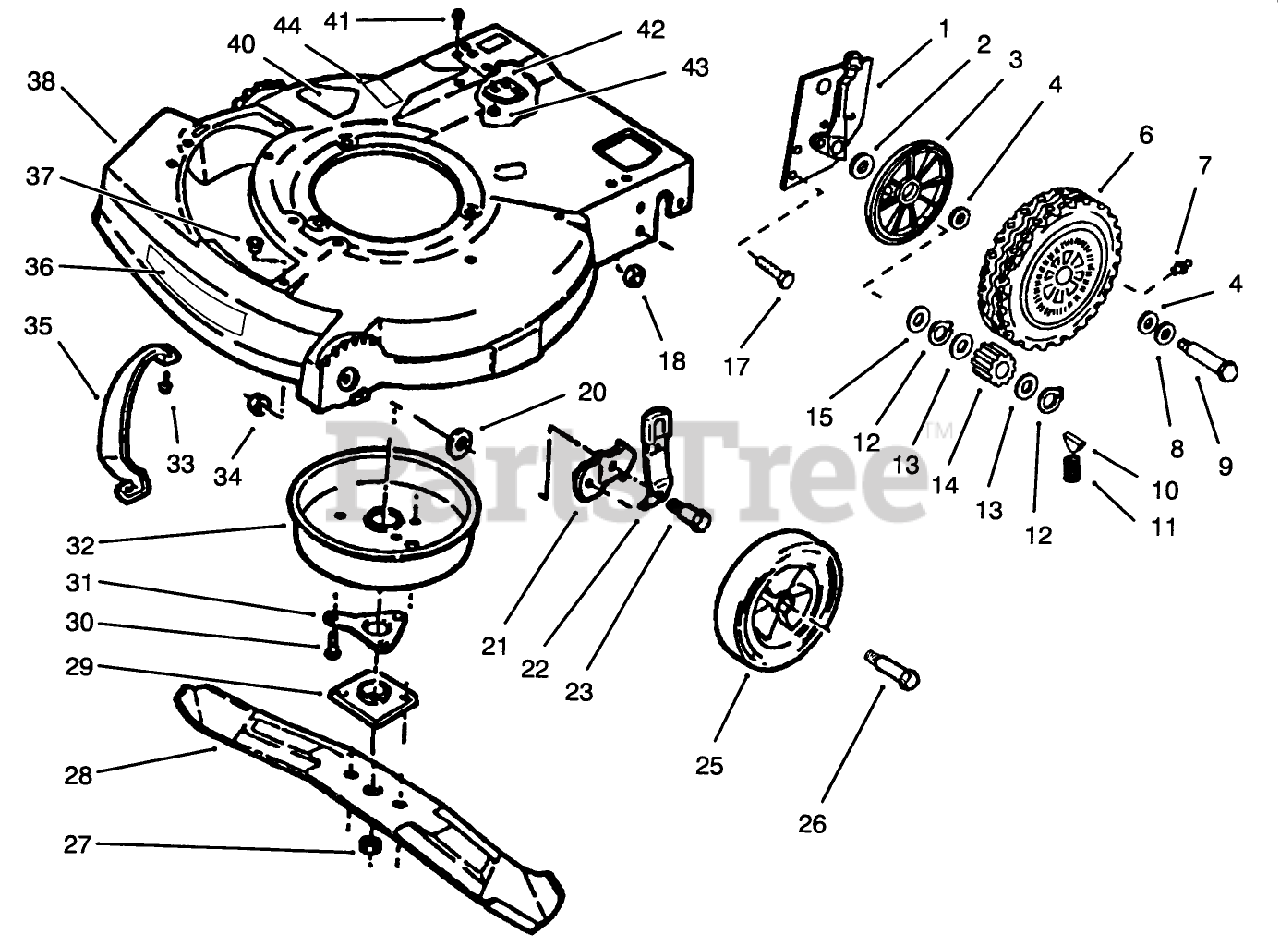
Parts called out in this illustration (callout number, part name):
1	Height Adjust Assy, L.H. (Incl. Ref. #27 28; p.2 )
4	WASHER-FELT
6	Wheel-Rear
7	FITTING LINCOLN
9	BOLT WHEEL
12	RET RING
13	SPACER/GR ALGHNY
14	PINION BROCKWAY
15	THRUST WASHER
17	SCREW - HEX
18	NUT-LOCK, NI
22	SPRING ARM ASM
26	BOLT-SHOULDER
27	NUT-BLADE
29	PLATE AND COLLAR ASM
31	SUPPORT F
32	MUFFLER COVER F
33	SCREW-HWH
35	BAR-TOE
38	HOUSING W/DECALS
40	DECAL-DANGER
42	BOLSTER
43	NUT-LOCK, NI
44	DECAL - WARNING
